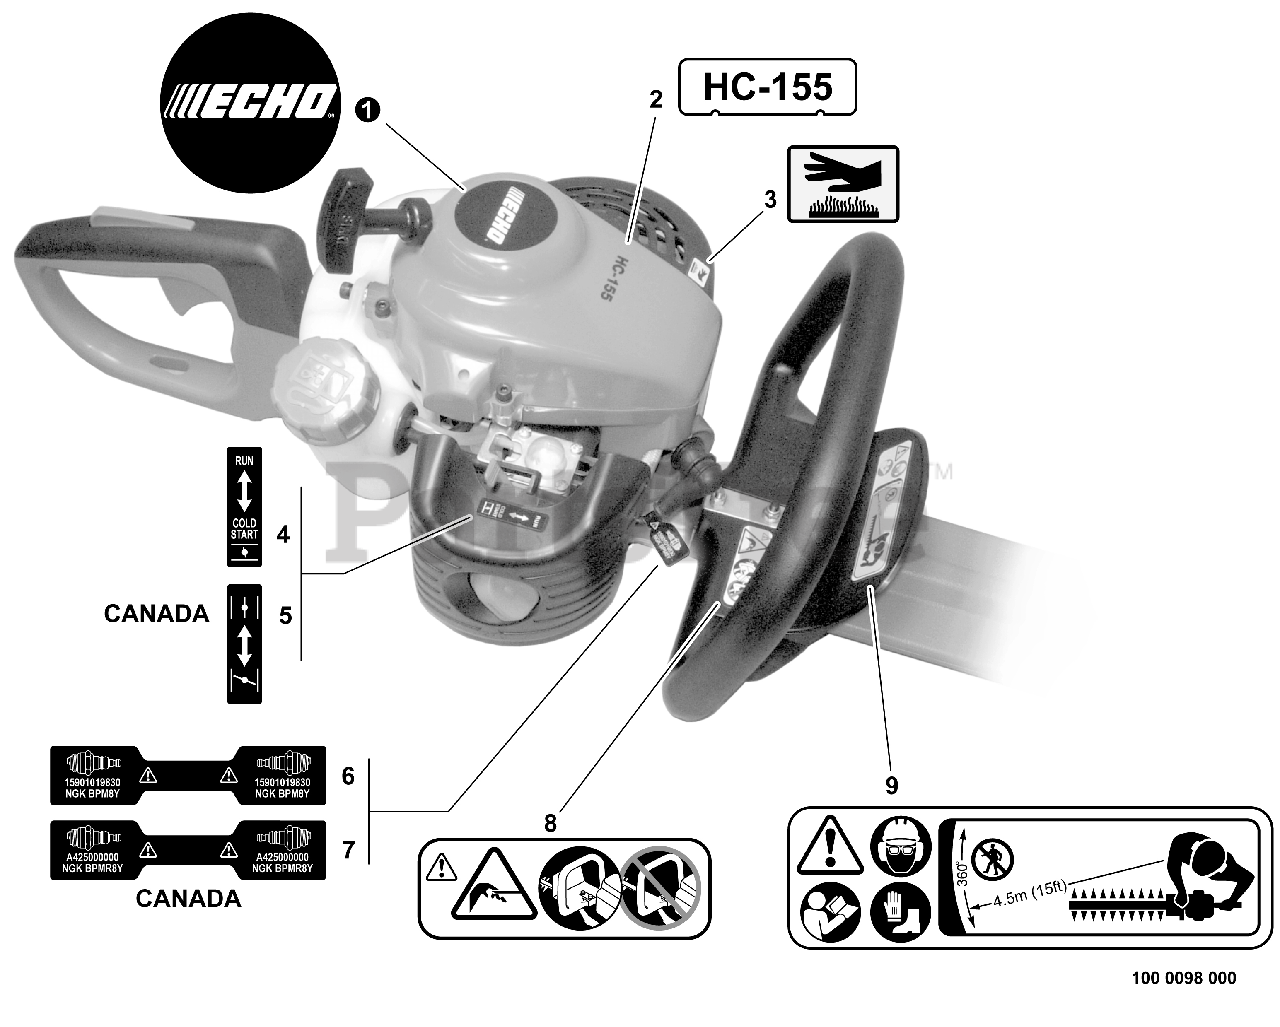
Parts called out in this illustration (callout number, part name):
1	LABEL - ECHO
2	LABEL - MODEL HC-155
3	LABEL - HOT SURFACE
4	LABEL - CHOKE
5	LABEL - CHOKE
6	LABEL - SPARK PLUG -- BPM-8Y
7	LABEL - SPARK PLUG -- BPMR-8Y
8	LABEL - CAUTION
9	LABEL - CAUTION
